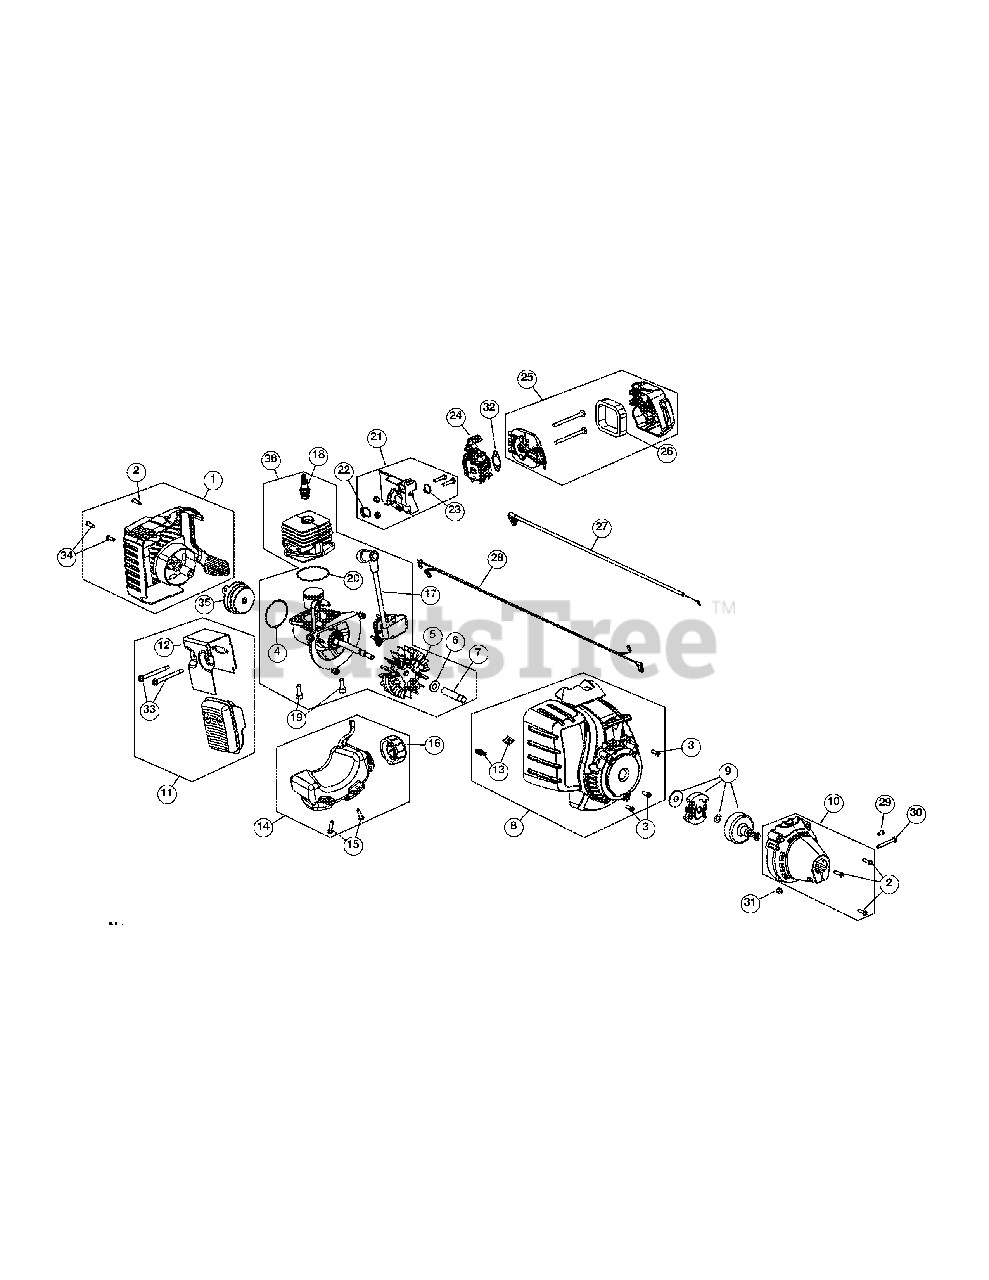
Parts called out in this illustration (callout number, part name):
1	Rear Cover Assembly (Incl Ref No. 2 & 34)
2	Cover Screw
3	Housing Screw
4	O-Ring
5	Flywheel Assembly
6	Washer
7	Spacer
8	Starter Housing (Incl Ref No. 3 & 13)
9	Clutch Assembly
10	Clutch Cover (Incl Ref No. 2)
11	Muffler Assembly (Incl Ref No. 12 & 33)
12	Muffler Gasket
13	U-shaped Nut
14	Fuel Tank Assembly (Incl Ref No. 15 & 16)
15	Tank Screw
16	Fuel Cap
17	Module Assembly
18	Spark Plug
19	Crankcase Bolt
20	Crankcase O-Ring
21	Insulator Assembly (Incl Ref No. 22 & 23)
22	Insulator O-Ring
23	Carburetor O-Ring
24	Carburetor
25	Aircleaner Cover Assembly (Incl Ref No. 26)
26	Aircleaner Filter
27	Throttle Cable
28	Lead Wires
29	Anti-rotation Screw
30	Clamp Screw
31	Clamp Nut
32	Air Cleaner Gasket
33	Muffler Screw
34	Rear Housing Screw
35	Electric Starter Cover Assembly
36	Short Block Assembly (Incl Ref No. 4-7 & 17-20)
